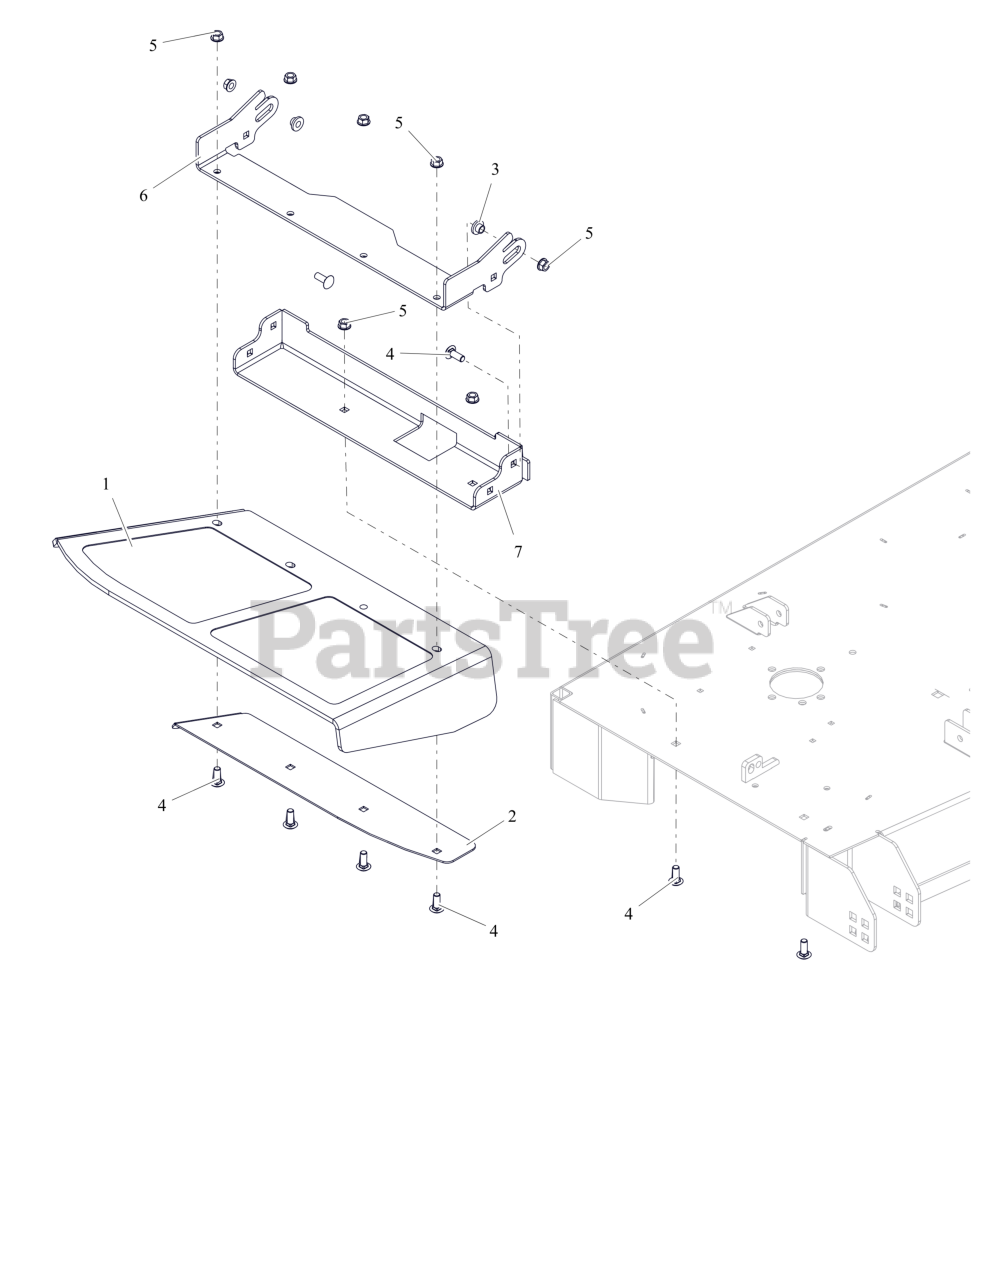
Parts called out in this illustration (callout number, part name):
1	CHUTE, FORMED RUBBER DISCH
2	DISCHARGE CHUTE CLAMP PLT -RED
3	BSHG-FLG .385X.500X.875X.406
4	BLT,RHSSN .38-16X1.00 G5 ZCC
5	NUT-LK-CTR-FLG .375-16 GF ZCC
6	BRKT, CHUTE MTG (RED)
7	BASE, DISCHARGE CHUTE MTG (RED) W/ SAFETY DECALS
